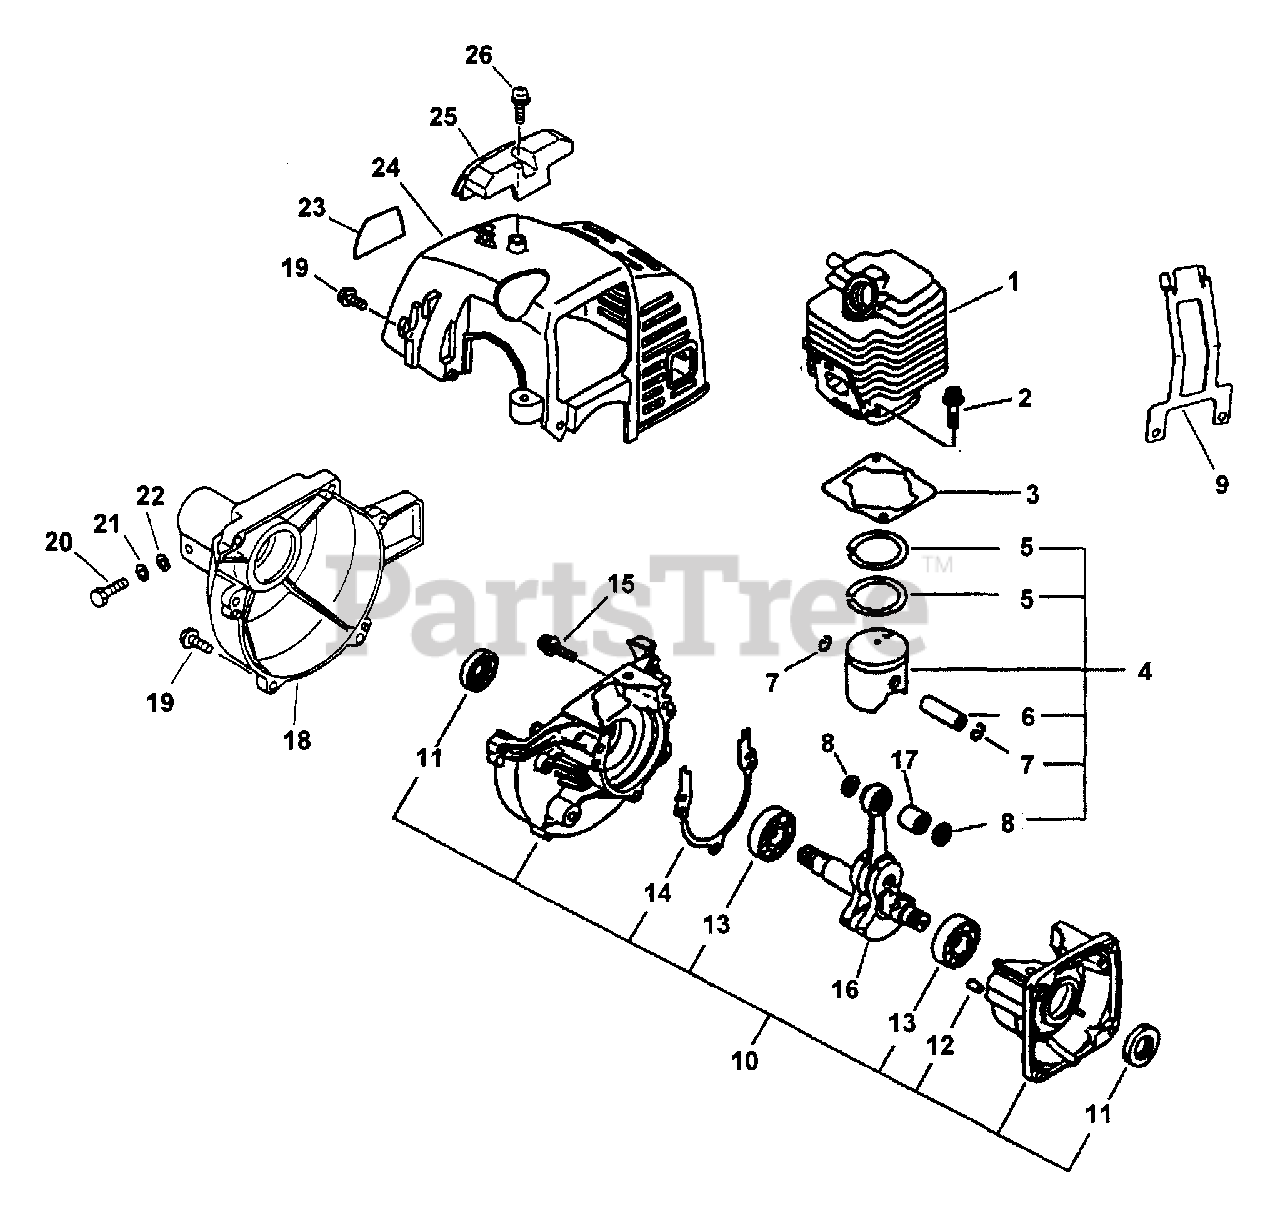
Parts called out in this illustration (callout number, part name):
1	CYLINDER
2	BOLT 5×22
3	GASKET, CYLINDER
4	PISTON KIT
5	RING, PISTON
6	PIN, PISTON 8
7	RING, SNAP
8	WASHER, THRUST
9	GUARD, ENGINE
10	CRANKCASE KIT
11	SEAL, OIL 12
12	PIN, LOCATING 4
13	BEARING, BALL - 6201 C3
14	GASKET, CRANKCASE
15	BOLT 5×28
16	CRANKSHAFT ASSY
17	BEARING, NEEDLE
18	CASE, FAN
19	BOLT 4×16
20	BOLT 5×25
21	WASHER, SPRING 5
22	WASHER, FLAT 5.5×10×0.8
23	LABEL - MODEL
24	COVER, ENGINE - ORANGE
25	GUARD, TOP - BLACK
26	SCREW 5×16
